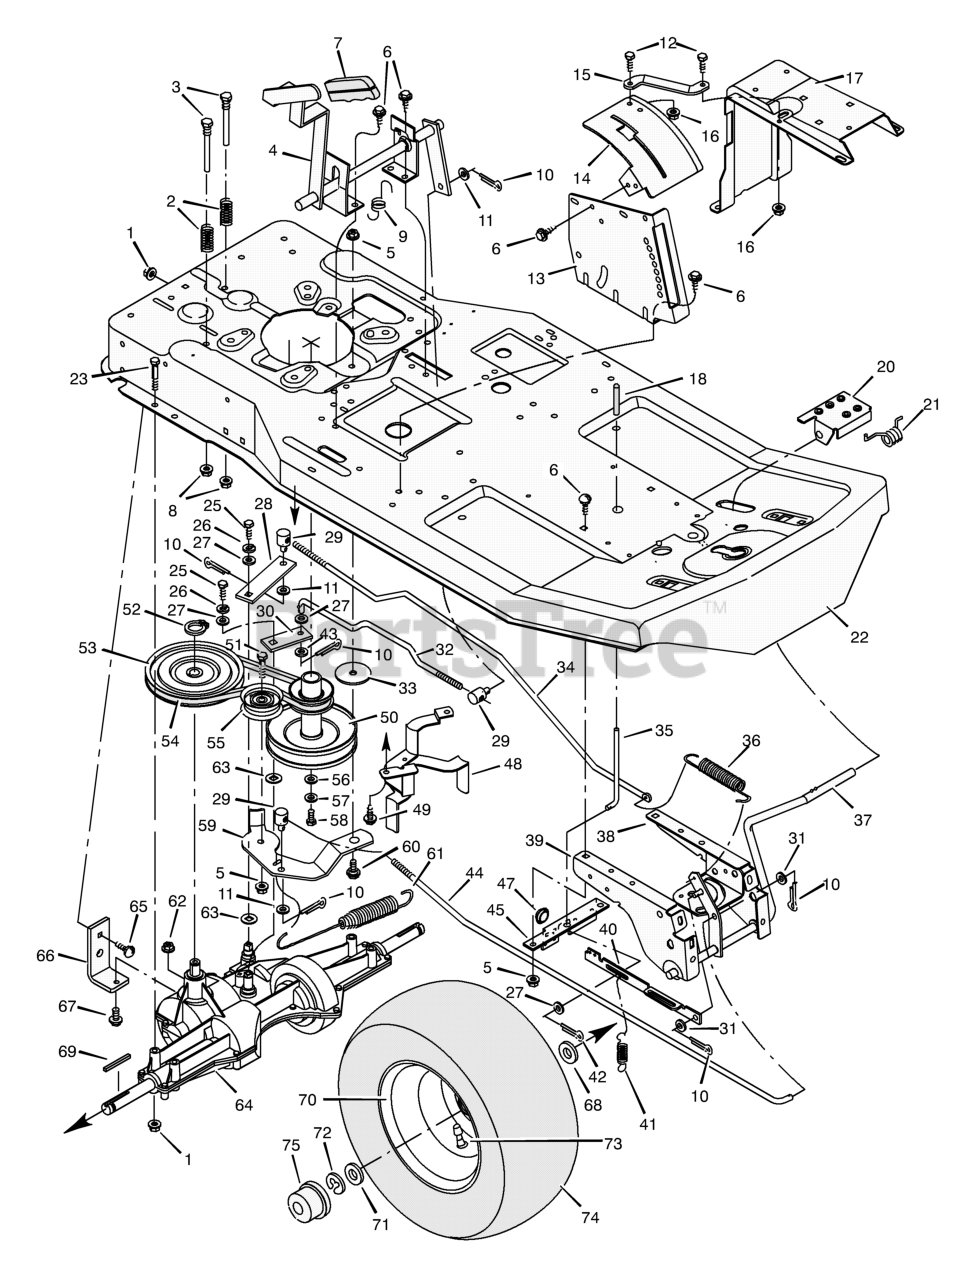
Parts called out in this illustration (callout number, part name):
1	Locknut, Flange
2	Spring, Compression
3	Guide, Belt
4	Shifter Assembly
5	Locknut, Flange
7	Grip, Shift Lever
8	Hex Nut
9	Spring, Extension
10	Pin, Cotter
11	Washer
12	Bolt, Hex
13	Plate, Index
14	Gate, Shift
15	Brace, Shift Gate
16	Locknut, Flange
17	Support, Seat
18	Grip, Parking Brake
21	Spring, Torsion
22	Frame Assembly
23	Bolt, Hex
25	Bolt, Hex
26	Lockwasher
28	Yoke, Brake
29	Nut, Adjusting
30	Yoke, Shift
31	Washer
32	Rod, Shift
33	Washer, Hardened
34	Rod, Brake
35	Rod, Parking Brake
36	Spring, Extension
37	Lever, Pedal
38	Plate, Left Suspension
39	Plate, Right Suspension
40	Link, Parking Brake
41	Spring, Extension
42	Pin, Cotter
44	Rod, Clutch
45	Stop, Parking Brake
47	Grommet
48	Guide, Belt
50	Pulley Assembly, Stack
51	Bolt, Hex
52	Ring, Retainer
53	Pulley, Drive
54	Belt, Motion Drive
55	Pulley, Idler
57	Lockwasher
58	Bolt, Hex
59	Bracket, Idler
60	Bolt, Shoulder
61	Spring, Extension
62	Locknut, Hex
64	Transaxle, Dana Model 4450-1 **
65	Bolt, Carriage
66	Bracket, Transaxle
67	Bolt, Hex
69	Key, Square
70	Wheel & Tire Assembly
73	Valve Stem
74	Tire *
75	Hub Cap
